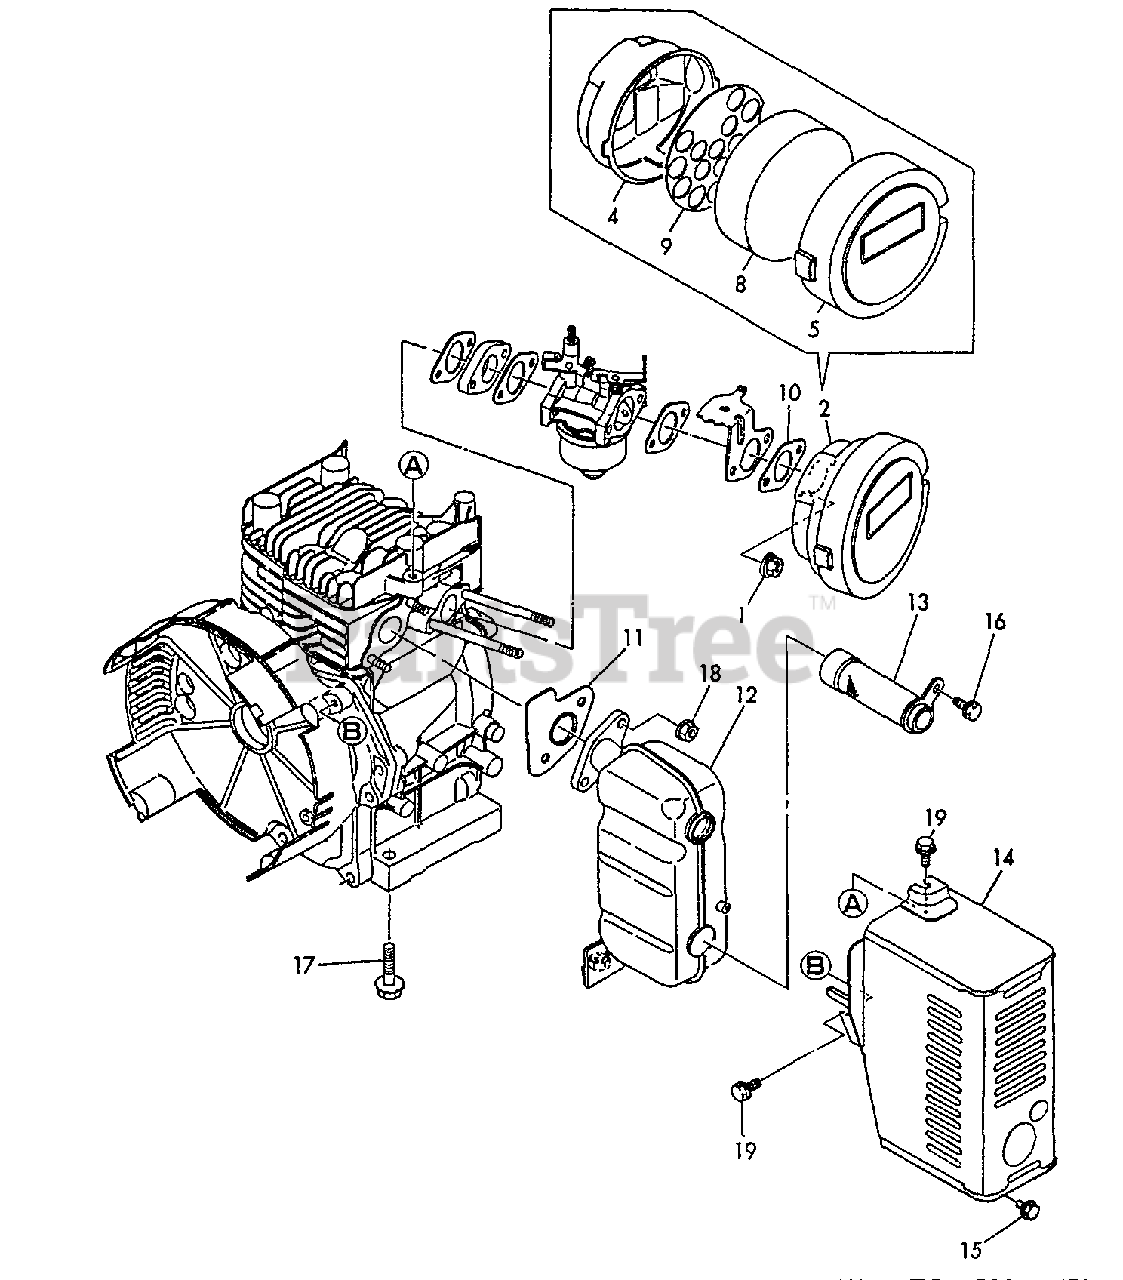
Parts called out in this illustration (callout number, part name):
1	NUT - 6 -- FLANGE
2	AIR CLEANER ASSY
4	CASE, AIR FILTER
5	COVER, AIR FILTER
8	FILTER, AIR
9	RETAINER, AIR FILTER
10	GASKET, INTAKE
11	GASKET, EXHAUST
12	MUFFLER
13	SCREEN, SPARK ARRESTOR
14	COVER, MUFFLER
15	BOLT - 6X8 -- PLATED
16	BOLT - 6X10 -- PLATED
17	BOLT - 8X30 -- PLATED
18	NUT - 6 -- FLANGE
19	BOLT - 6X8 -- PLATED
